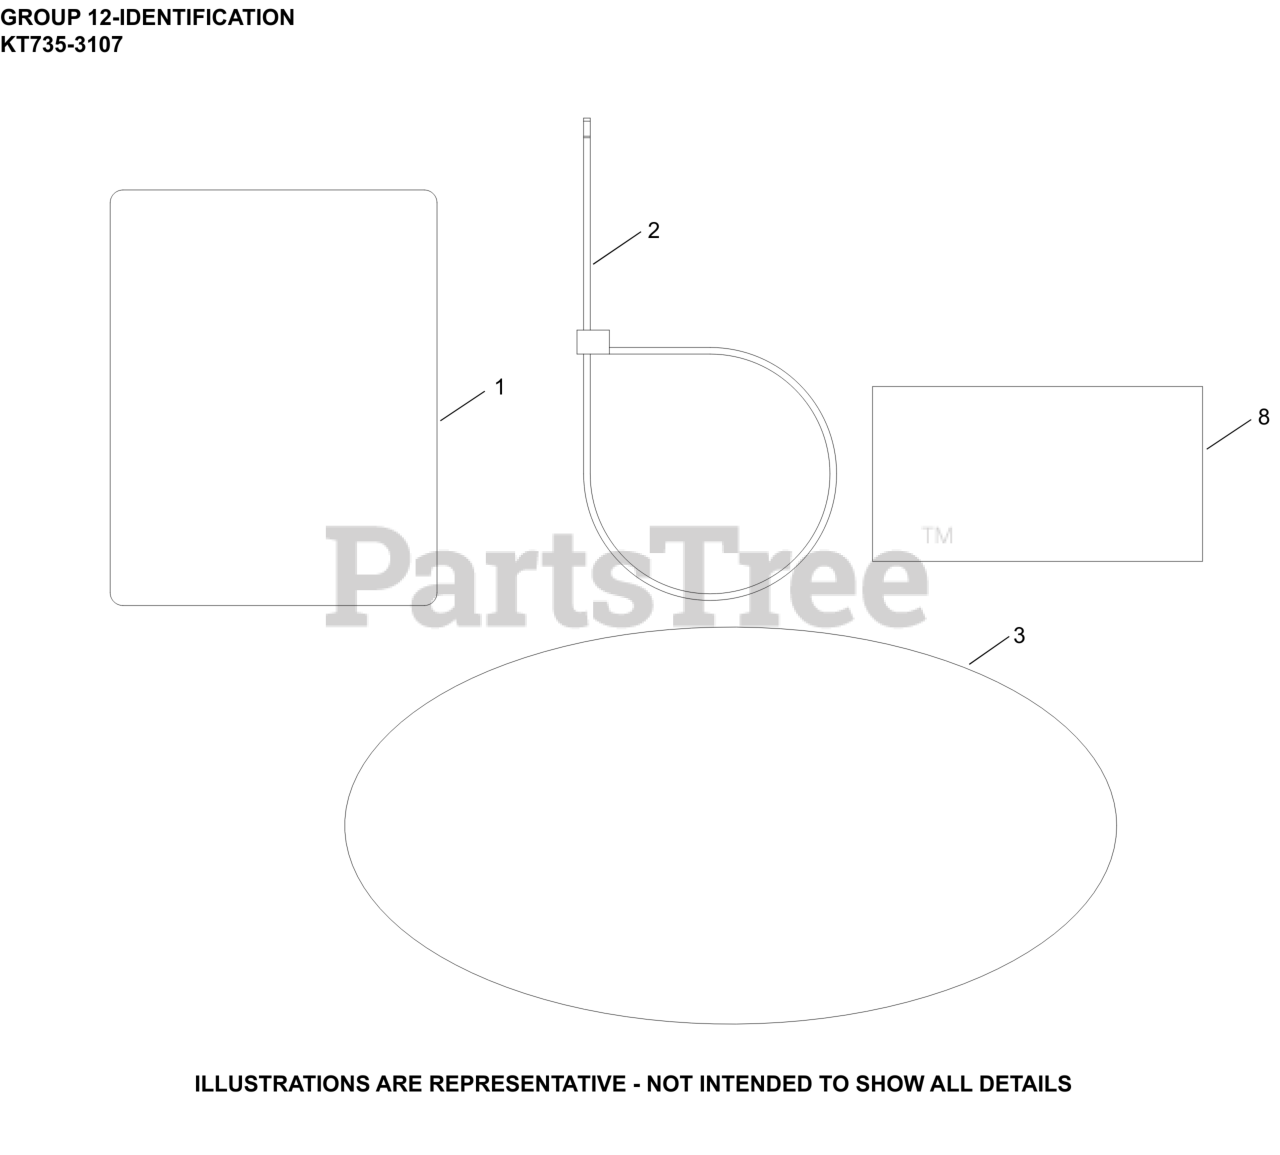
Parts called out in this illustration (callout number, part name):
1	LABEL, CLEAR LAMINATION
3	LABEL, 7000 SERIES KT735 (24 HP)
8	DECAL, USA
